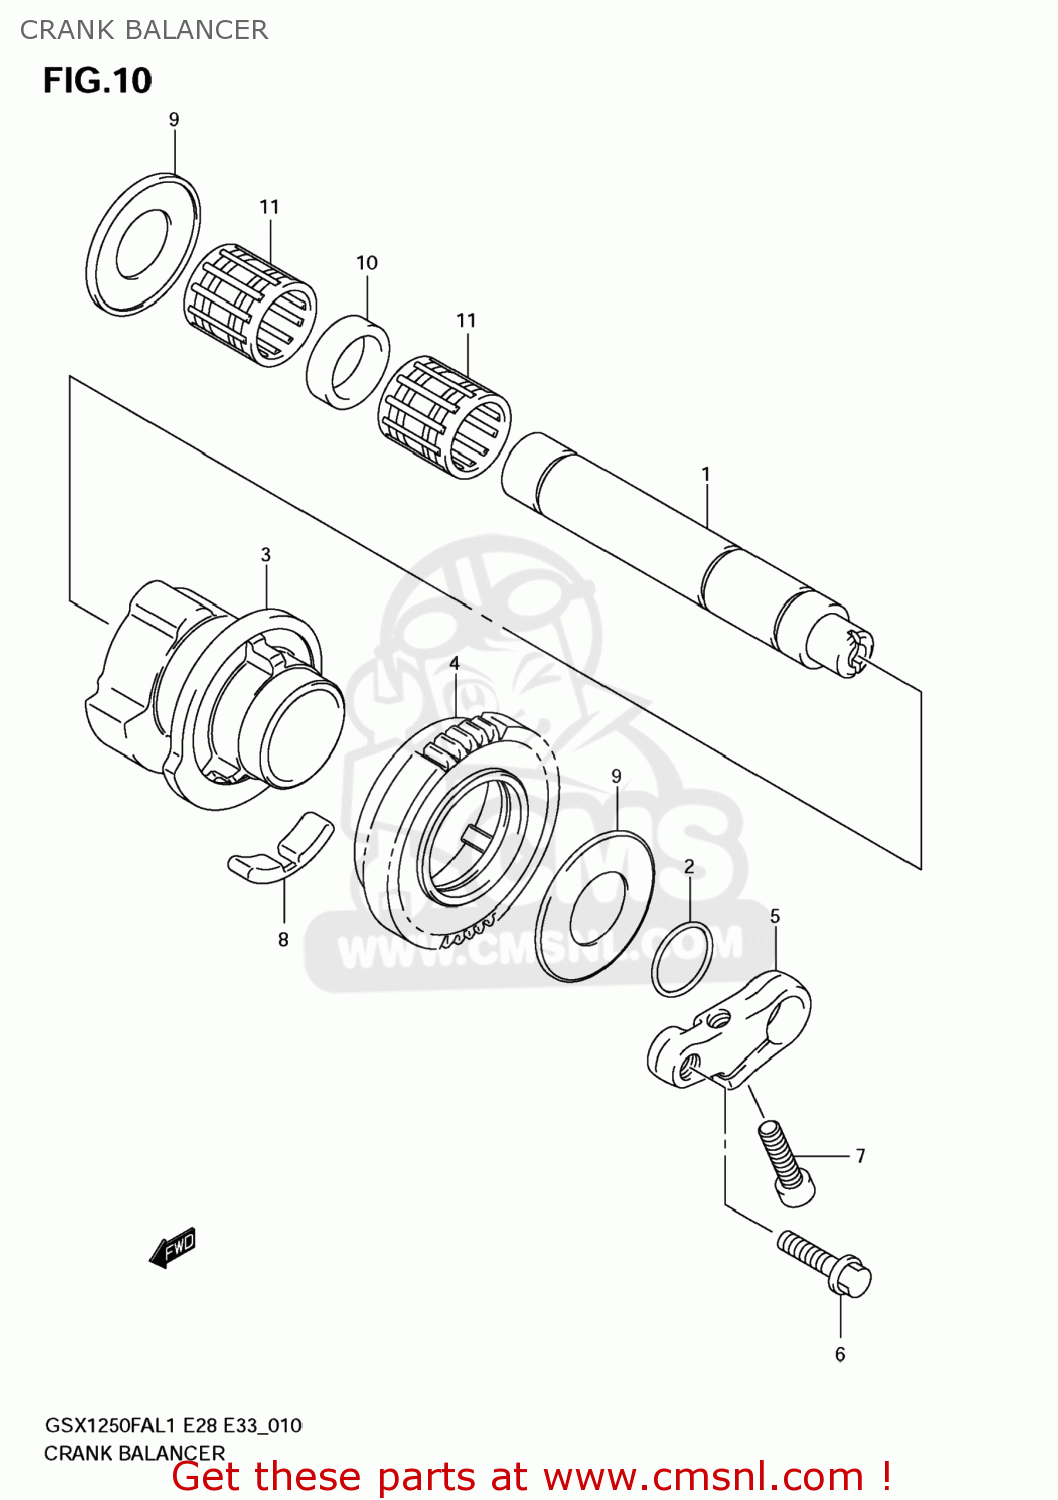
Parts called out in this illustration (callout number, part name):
1	SHAFT,CRANK BALANCER
2	O RING(D:1.9,ID:16.8)
3	BALANCER,CRANK
4	GEAR,CRANK BALANCER
5	ARM,BALANCER SHAFT
6	BOLT(6X20)
7	BOLT
8	DAMPER,CRANK BALANCER GEAR
9	WASHER
10	SPACER(19X26X8.6)
11	BEARING(19X26X25.2)
